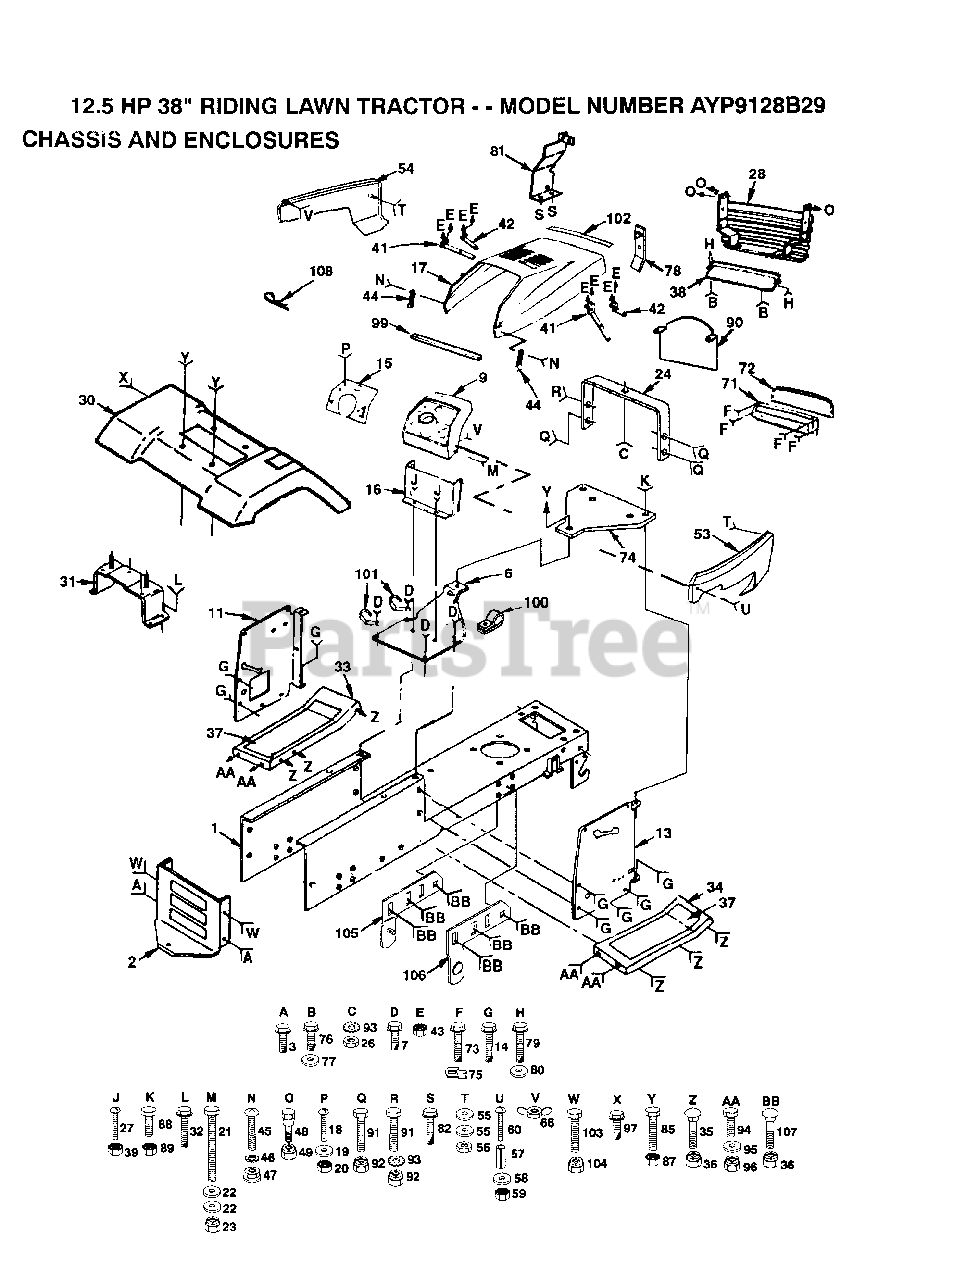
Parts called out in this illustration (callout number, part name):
2	DRAWBAR LT/YT
3	SCREW
7	SCREW LT
11	DASH PANEL LH
12	COVER ACCESS
14	SCREW
18	SCREW
19	WASHER
22	WASHER
24	SUPPORT ASS'Y
25	LOCKWASHER
27	SCREW
32	SCREW
35	BOLT
37	"PAD,FOOTREST"
43	NUT
44	HOOD LATCH T
45	SCREW
46	LOCKWASHER
47	WELDNUT
55	WASHER PM
57	SPACER LT
58	WASHER
60	SCREW
72	LENS LT
74	PLATE SUPPORT BATTERY
75	"""J"" FASTENER LT"
76	SCREW
77	WASHER
79	SCREW HEX CRT
80	WASHER
82	SCREW
84	WASHER PM
85	BOLT
86	SPACER
89	NUT
90	BAFFLE HOOD VERT
95	WASHER
97	SCREW LT
100	CLIP T
101	"CLIP,INSULATOR"
105	BRKT ASM PIVOT LH
106	BRKT ASM PIVOT RH
107	BOLT
108	SPRING.RETAINER
